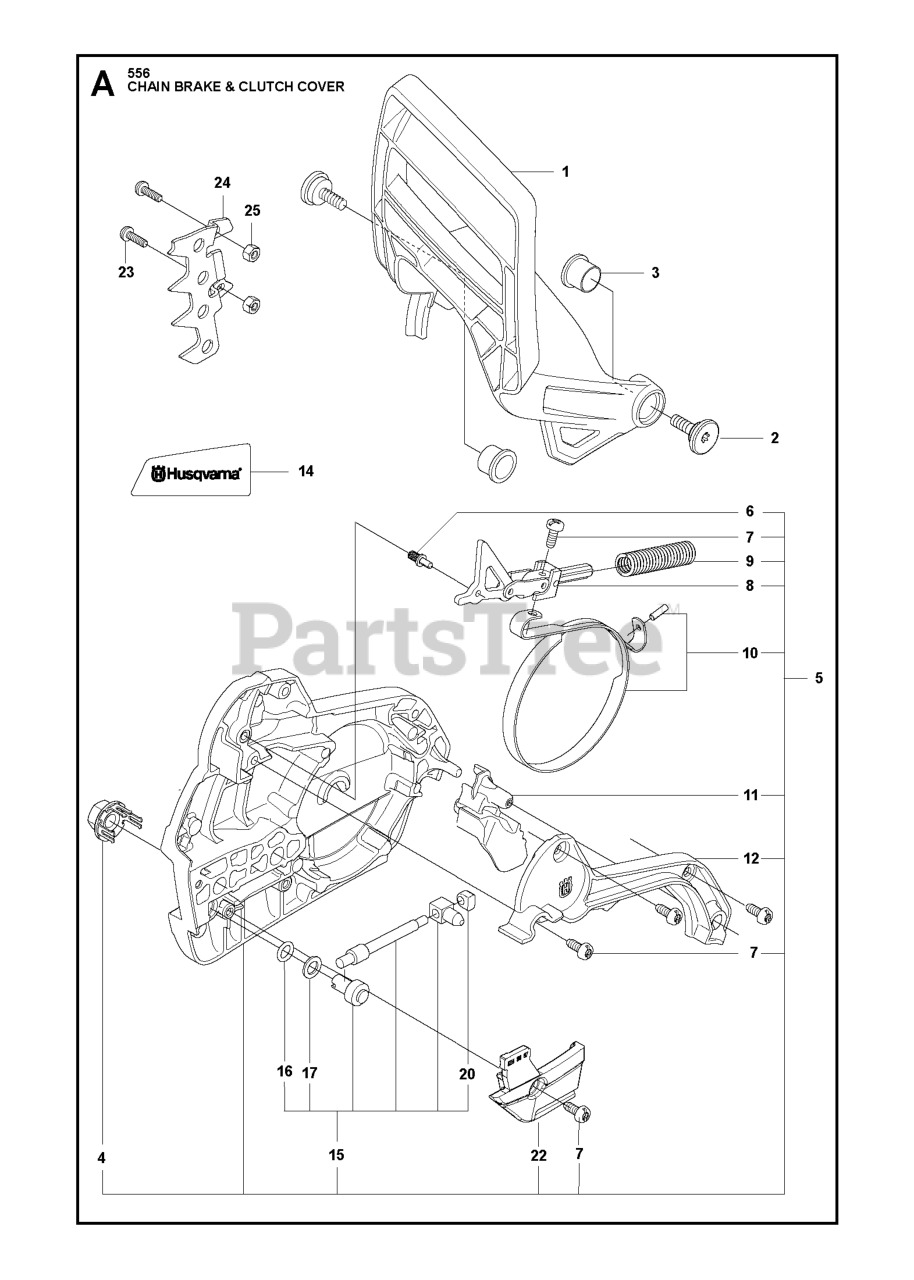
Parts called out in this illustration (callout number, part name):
1	DECK SVC 107HP.EZMUL.498
2	PALNUT 1/4
3	NUT LOCK HEX FLANGE 5/16-18
5	BOLT.5/16HEX.WHS.HD
11	SCREW.1/4-20X5/8
13	BOLT.3/8-16X1.50
14	KEEPER, BELT IDLER
16	NUT LOCK FLG 3/8-16 UNC
17	NUT.FLANGE.LOCK.TOP
19	BEARING.MANDREL.TOP.EXTENDED
20	SCREW, WASHER HEAD
23	SCREW LT
27	BELT.ELECT.MOWER.DRIVE 97.8 EL
32	SPRING 107CM & 97CM ELECTRIC D
33	RP.HOUSG.MAND.REV.TALL.N/GRS
34	SHAFT ASM.MNDRL.N/GREASEABLE
35	BLADE.107.LH.SINGLE.NON.QD
42	SCREW
43	PULLEY PULLEY MANDREL 5.438 PD
45	RP HOUSING.MANDREL.REV.REVS.
47	SCREW.SEMS.7/16-20X1.HEX.HEAD
72	RP.CHUTE 107/97 TEX GENII
75	FLAT IDLER PULLEY
76	PORT.WASHOUT
84	KEEPER KEEPER. LH MANDREL BELT
85	BLADE.107.RH.SINGLE.NON.QD
86	BOLT.3/8-24X1.25GR8. LHTHRD
87	LOCKWASHER
88	WASHER.BLADE
91	WASHER
94	BRKT.CLUTCH.CABLE
95	SCREW, 3/8-16X3/4
96	SPACER
97	PROTECTOR
98	STUD.FASTNER.W/ANTI-ROTATE
99	ARM.SUSPENSION.MOWER.R
100	BOLT.SHOULDER
101	NUT.CROWNLOCK.9/16 -18.UNC
102	SPACER BEARING
104	COVER.MANDREL.107.RH.GEN.2
105	COVER.MANDREL.107.LH.GEN.2
110	CRD.SPUR.GEAR
111	GASKET GASKET GEARCASE
112	SHAFT SHAFT. CRD GEARCASE ADAP
113	PLUG PLUG OIL
114	VALVE VALVE RELIEF
115	SCREW
116	BOLT.CARIGE.SS.1/4-20X1.75GR5
117	NUT T
118	ARM ARM. CLUTCHING 107 TEX CRD
119	GEARCASE GEARCASE SUBASM
120	KEEPER KEEPER. RH MANDREL BELT
121	WASHER WASHER
124	SUB.ASM.REVERSE.THREAD.REV
125	BRACKET
127	BOLT.SHOULDER.3/8-16X3-5/8.
128	RP WHEEL. GUAGE RALLY
129	ROD ROD. SWAY CRD GEN II
130	WASHER
131	PIN.COTTER.5/16.BOW TI
143	COVER DOOR.107 CM CRD EZ MULCH
144	PIN PIN.HINGE
145	E-RING.5/16"
146	SPRING SPRING: EZ MULCH DOOR
154	SCREW T-30 1/4-20 X
159	PLATE.107CRD.LH.SIDE.BLTON
160	PLATE.107CRD.LH.FRONT.BOLT-ON
161	PLATE.107CRD.RH.FRONT.BOLT-ON
162	PLATE.107CRD.RH.SIDE.BOLT-ON
163	BOLT
